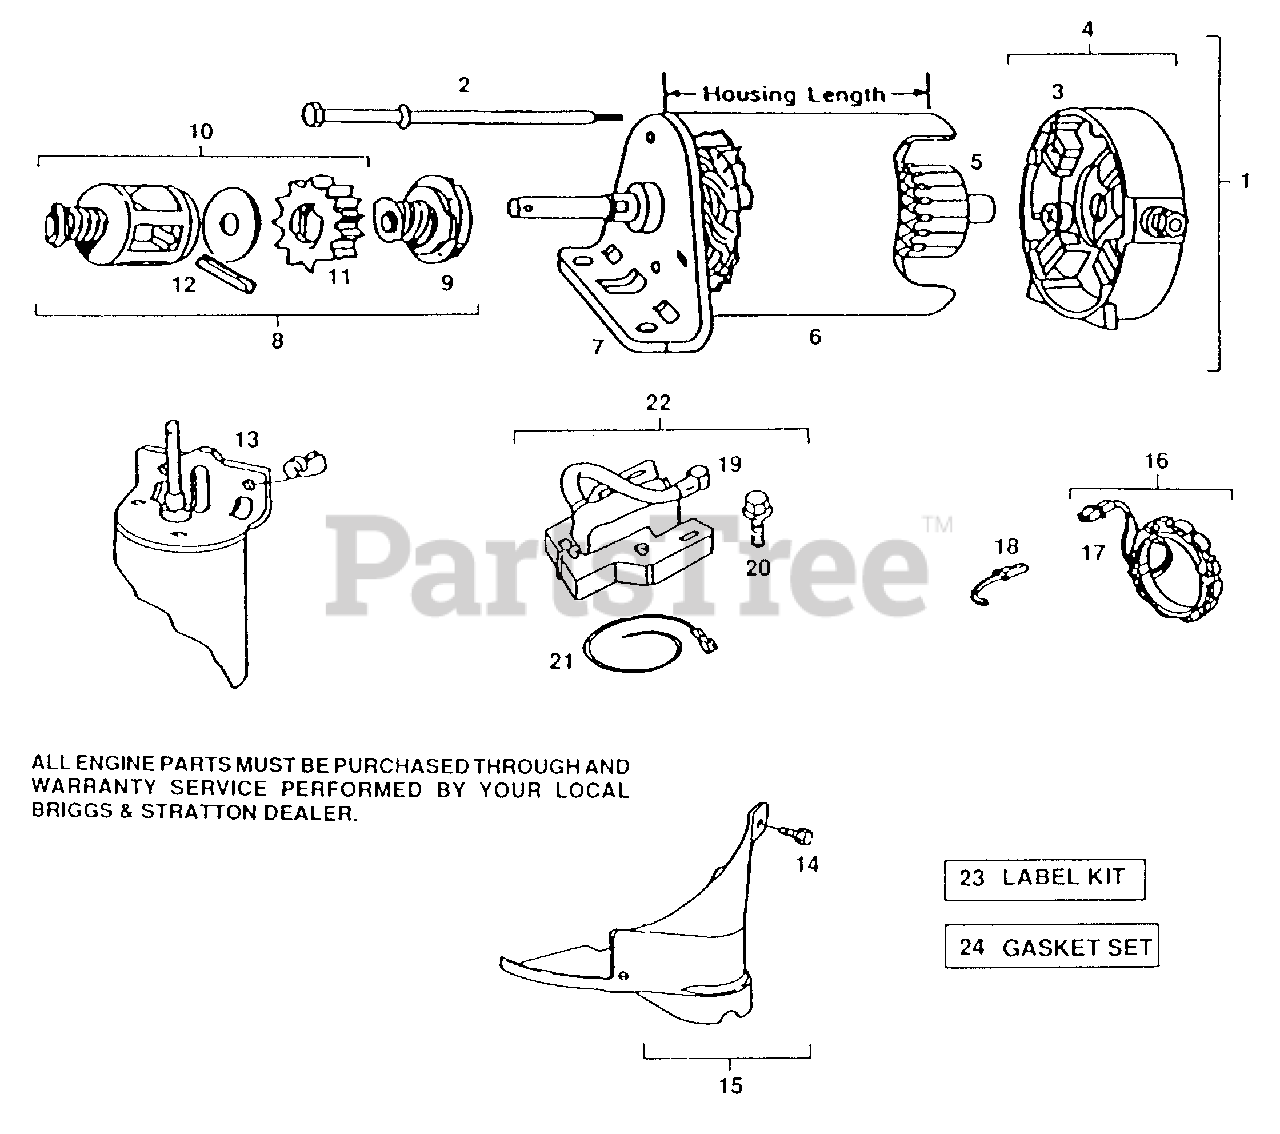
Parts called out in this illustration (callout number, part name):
1	Motor and Drive Assembly 12V, 4 3/8" Housing Length
2	Thru Bolt Assembly
3	Brush Assembly
4	End Cap Assembly Commutator
5	Armature Assembly
6	Housing Assembly
7	Drive End Cap Assembly
8	Drive Assembly
9	Clutch Assembly
10	Retainer and Pin
12	Roll Pin
13	Screw, Sem
14	Screw, Sem
15	Cover, Starter
16	Stator, Alternator (Dual Circuit)
17	Diode and Connector Assembly (Dual Circuit)
18	Alternator Harness Assembly (Dual Circuit)
19	Terminal, Ignition
20	Screw, Armature Mounting Sem
21	Wire, Ground
22	Armature, Magneto
23	Decal, Label Kit
24	Gasket Set
